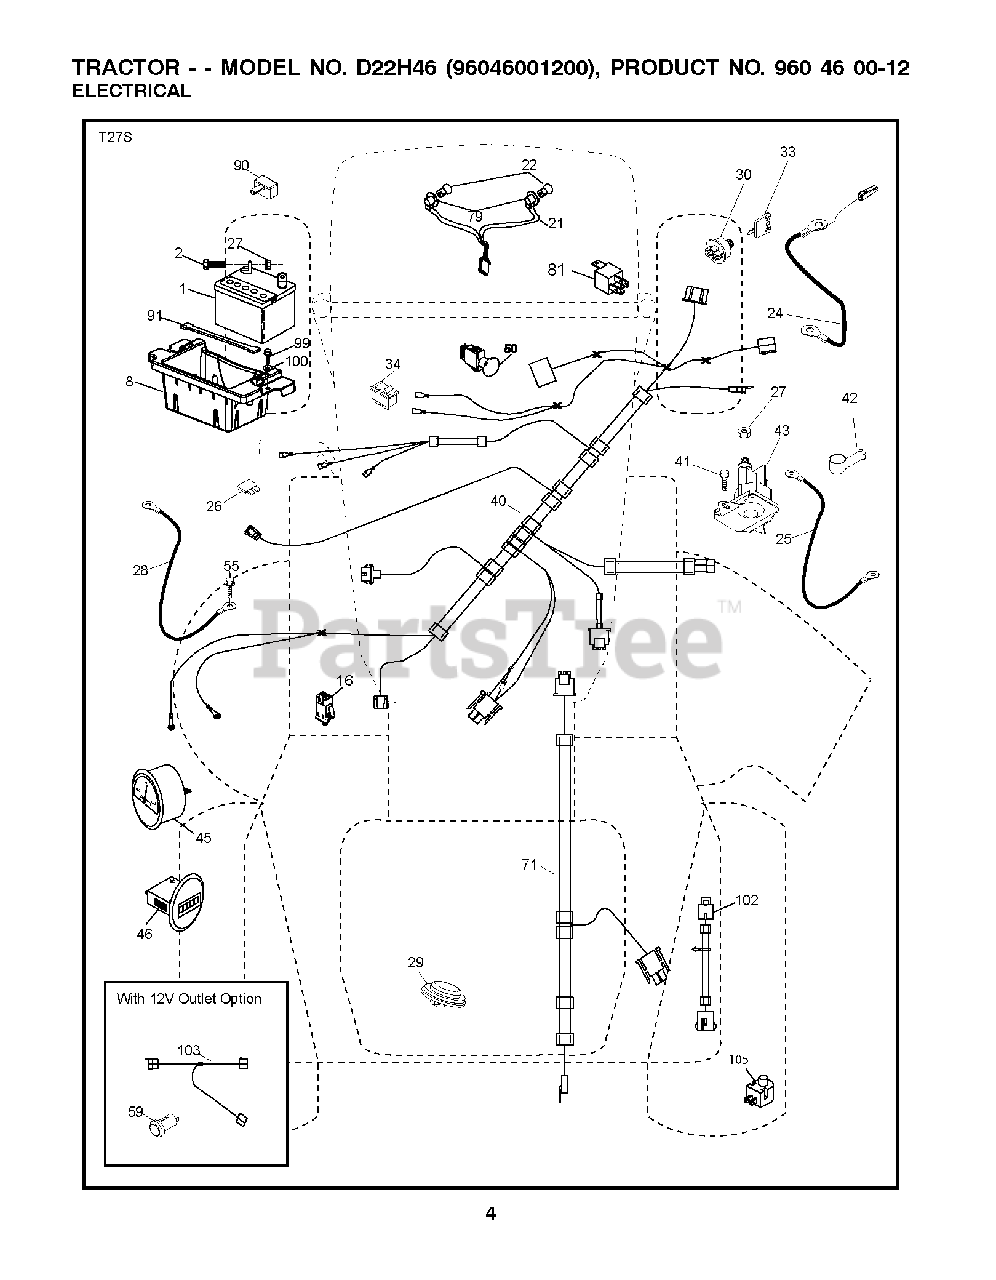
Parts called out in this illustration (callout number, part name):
1	REPL BY 532 12 38-99
2	BOLT.HEX.1/4.X.3/4.DICHROMATE
8	BOX.BATTERY.MOUNT.FRONT.LT
16	SWITCH INTERLOOK PUSH-IN
21	HARNESS.W/LIGHT SOCKET
22	LIGHTBULB
24	CABLE.BATT.POS.WIRE.TG.DA SOL
25	CABLE.STARTER.6G.BL/RED.17.5
26	FUSE 20AMP
27	NUT
28	CABLE GROUND 6 GA 21" 90T BLK
29	SWITCH.SEAT.DELTA.OPC.
30	SWITCH.IGN.DELTA.W.LGH.ROS
33	KEY.CHAIN.BLISTER.PACK.GEN.USA
34	SWITCH LT
40	HARNESS.IGN.ELE.RELAY.RND.TEX
41	SCREW
42	TERMINAL COVER
43	SOLENOID.W/BRASS.PLUNGER
45	AMMETER.ROUND.SNAPIN
46	HOURMETER.ROUND.SNAPIN
50	PTO SWITCH
55	SCREW 5/16"
71	HARNESS-CHASSIS SUB
79	BULB HOLDER ASM.
81	RELAY HARNESS.SEALED
90	COVER.TERMINAL.BATTERY
91	STRAP.BATTERY.MOUNT.FRONT
99	SCREW HEXWSHR 1/4-20X3/4
102	HARNESS PIGTAIL PCH TEX ROS
105	REVERSE SWITCH
